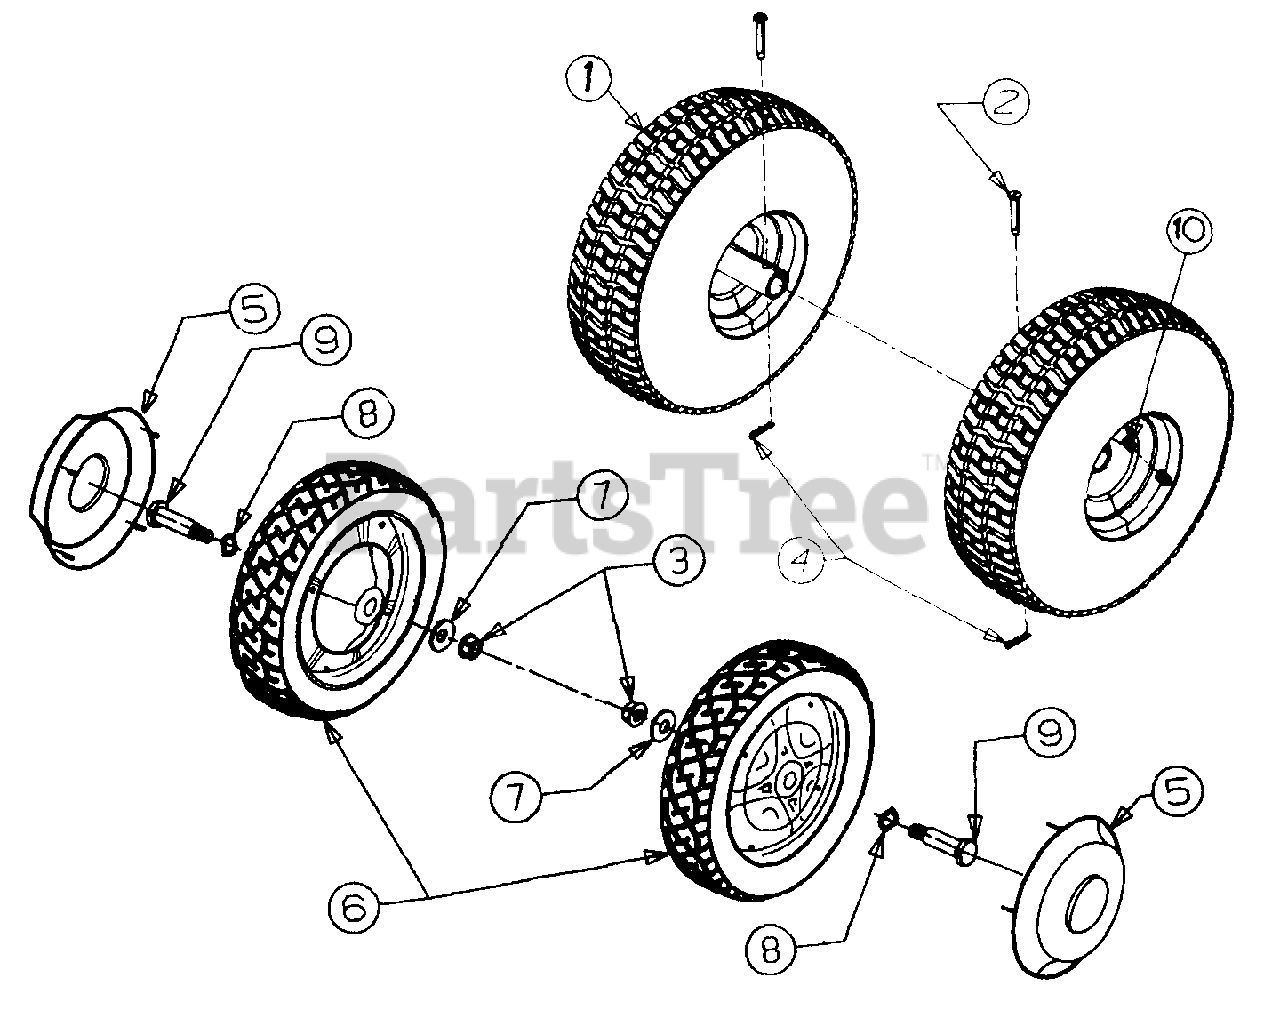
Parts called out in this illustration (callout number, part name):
2	PIN-CLEVIS
3	NUT-HEX FLANGE
4	PIN-COTTER
5	HUB CAP
6	WHEEL 2" X 8"
7	WASHER-BELL
8	WASHER-WAVE
9	SCREW-SHOULDER
10	VALVE STEM
